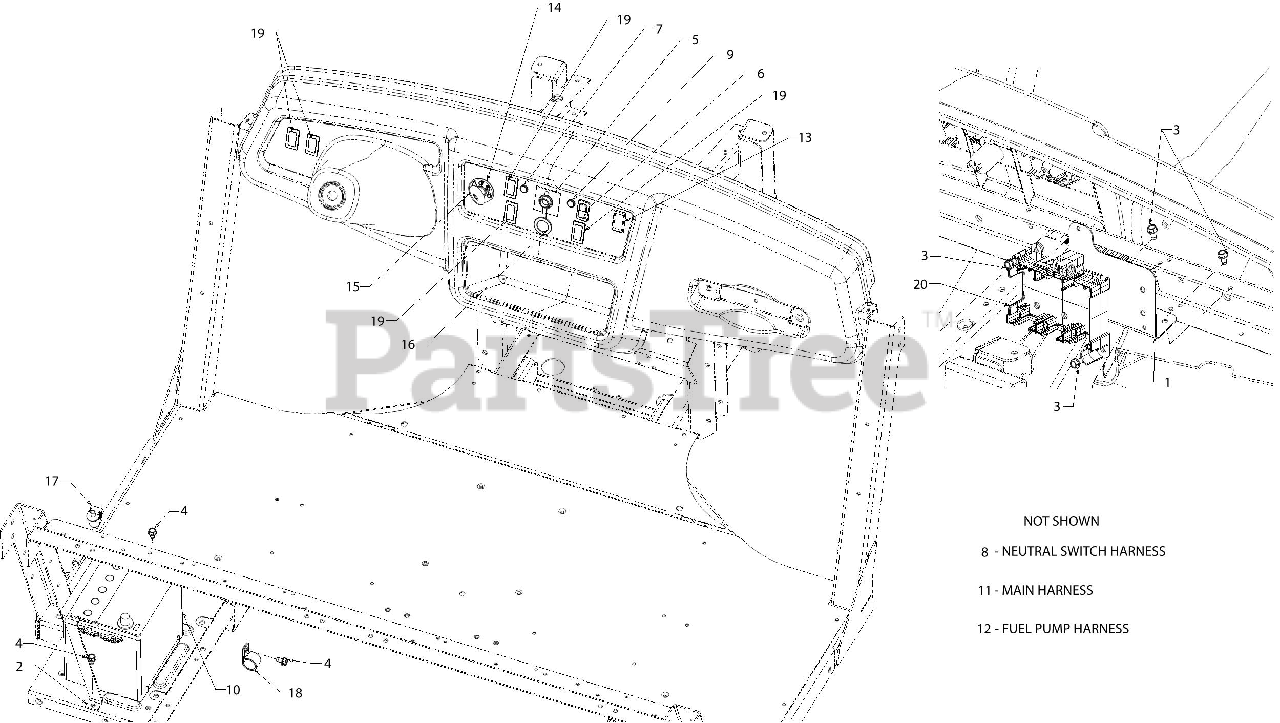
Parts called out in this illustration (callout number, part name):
1	FUSE MOUNT BRACKET
2	BATTERY MOUNT BRACKET
3	SCREW 1/4-20 X.500
4	SCREW 5/16-18 x .500
6	4X4 ROCKER SWITCH
7	GREEN INDICATOR LAMP
9	INDICATOR LIGHT-RED
10	BATTERY-540 CCA
14	IGNITION SWITCH
15	IGNITION KEY
16	POWER RECEPTICAL
17	SNAP MOUNT SWITCH
18	HOSE CLAMP 1.0"
19	PANEL SWITCH PLUG
20	3 WAY RELAY HOLDER
